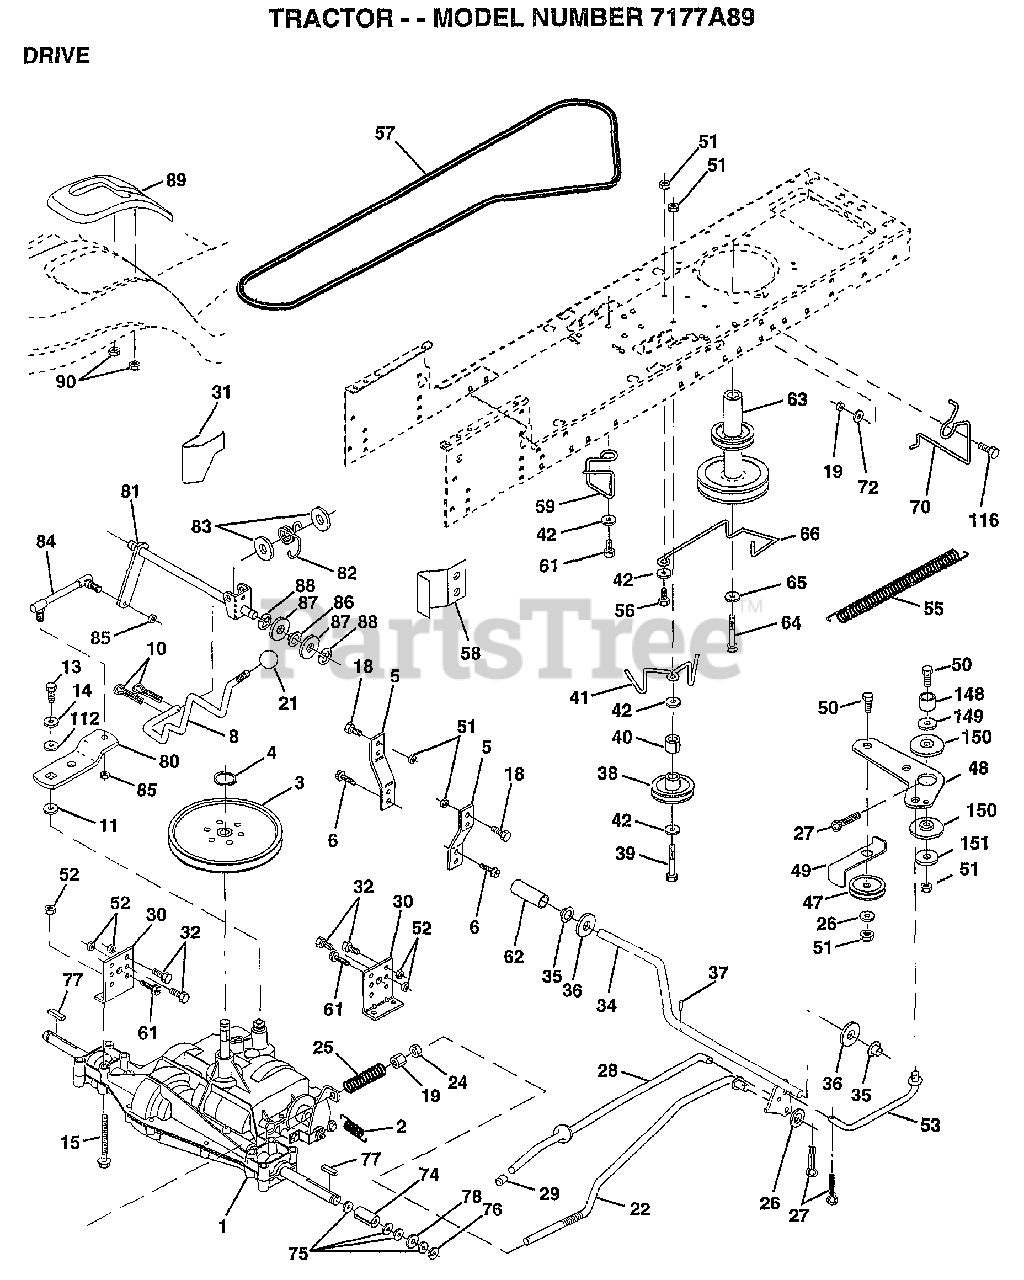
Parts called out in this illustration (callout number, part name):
2	SPRING.BRAKE.RETU
3	PULLEY TRANS
5	STRAP TORQUE
6	SCREW
8	"ROD SHIFT,FENDER"
10	PIN COTTER 1/8
11	WASH-SHFT PLT LT
13	BOLT.1/4-28.W/PAT
14	LOCKWASHER
15	BOLT.HX.FLG.5/16
18	BOLT
19	NUT
21	KNOB T (1/2-HOLE)
22	BRAKE ROD
24	NUT
25	SPRING ROD LT
26	WASHER
27	COTTER PIN
28	ROD.BRAKE.PARK.LT
30	TRANSAXLE MTG BKT
31	"KEEPER,BELT LH T"
32	BOLT
34	SHAFT ASM-PEDAL F
35	NYLON BEARING
36	WASHER LT
38	PULLEY.IDLER.FLAT
39	BOLT
40	SPACER T
42	WASHER
48	BELLCRANK.CLUTCH
49	RETAIN BELT
53	"LINK, CLUTCH T"
55	"SPRING, RETURN LT"
57	"V-BELT,95.3"
58	"KEEPER,BELT RH T"
59	KEEPER BELT CNTSP
61	SCREW
62	PEDAL COVER T
63	PULLEY.ENGINE
64	BOLT
65	LOCKWASHER
66	KEEPER-BELT
70	KEEPER BELT ENG
72	WASHER
74	SPACER LT
75	WASHER
76	E-RING LT
77	SQUARE KEY
78	WASHER
80	ARM.SHIFT.TRANS.
81	SHAFT ASSY CROSS
82	"SPRING,TORSION"
83	WASHER
84	"ROD.TIE.20""P930LT"
85	NUT.CNT.LOCK.1/4
86	BUSHING
87	WASHER D
88	KLIP RING
90	NUT
112	WASHER LT
116	BOLT RDHD 3/8-16
149	SPACER RETAINER
150	BUSHING.NYLON
151	WASHER
